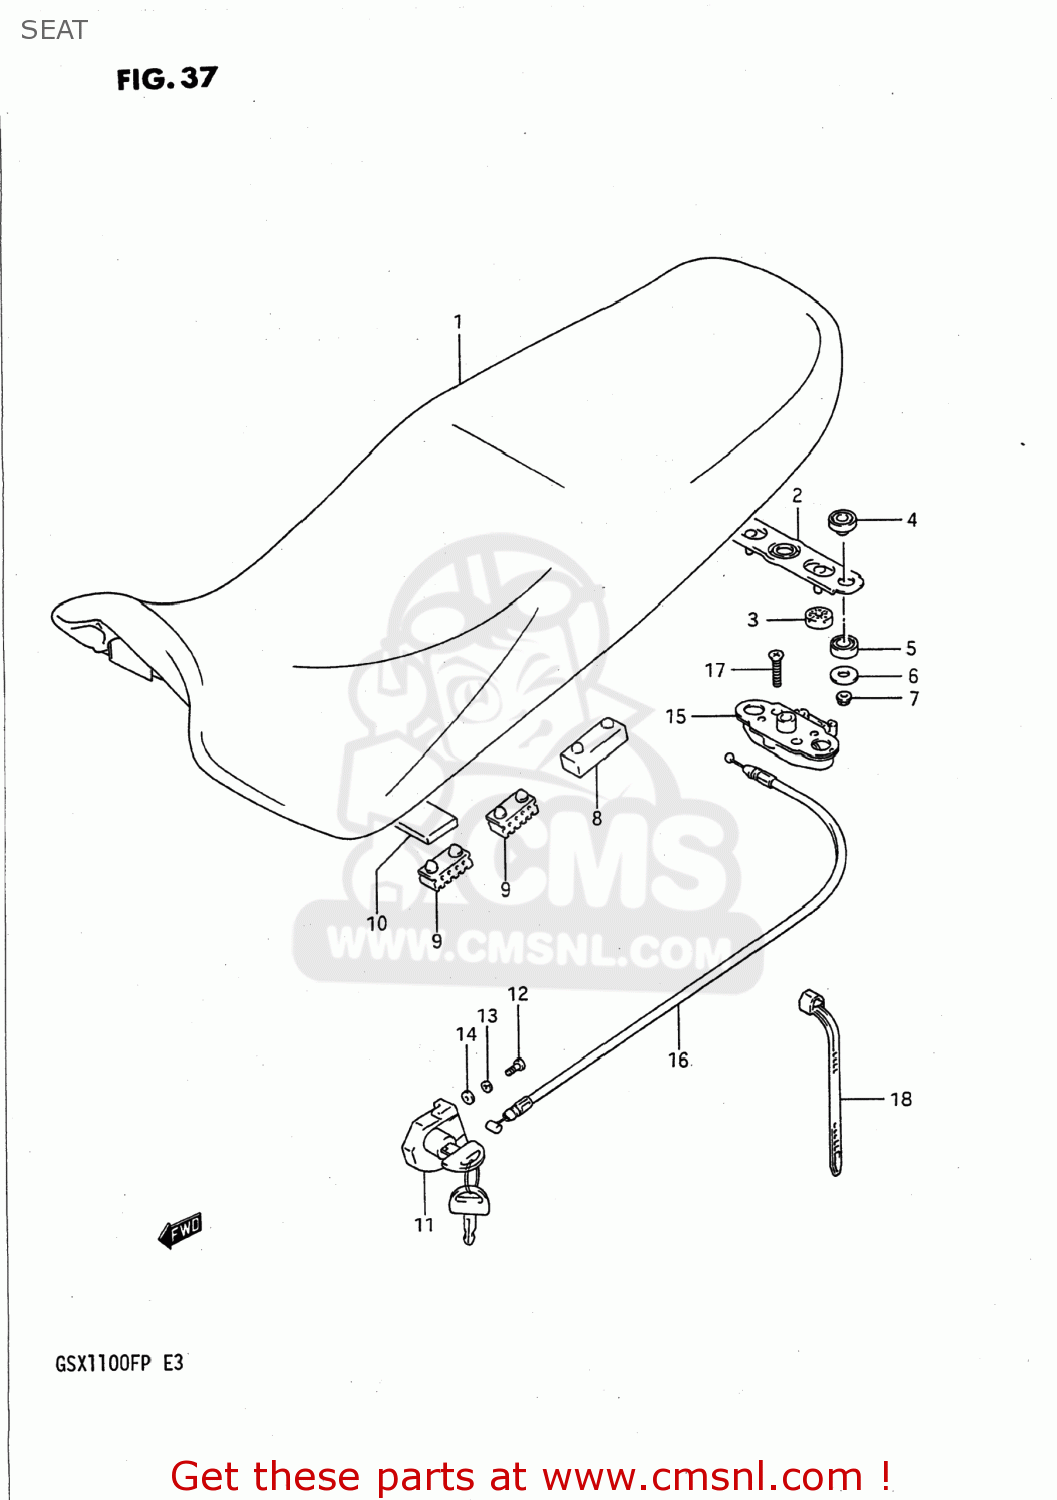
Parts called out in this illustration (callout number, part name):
1	SEAT ASSEMBLY
2	STRIKER,SEAT LOCK
3	CUSHION
4	CUSHION
5	CUSHION
6	WASHER
7	NUT
8	CUSHION,SEAT
9	CUSHION,SEAT
10	CUSHION(30X60X10)
11	LOCK SET
12	SCREW
13	WASHER,LOCK
14	WASHER,5MM
15	BRACKET,SEAT SUPPORT,RIGHT
16	CABLE,SEAT LOCK
17	SCREW
18	CLAMP(L:125)
